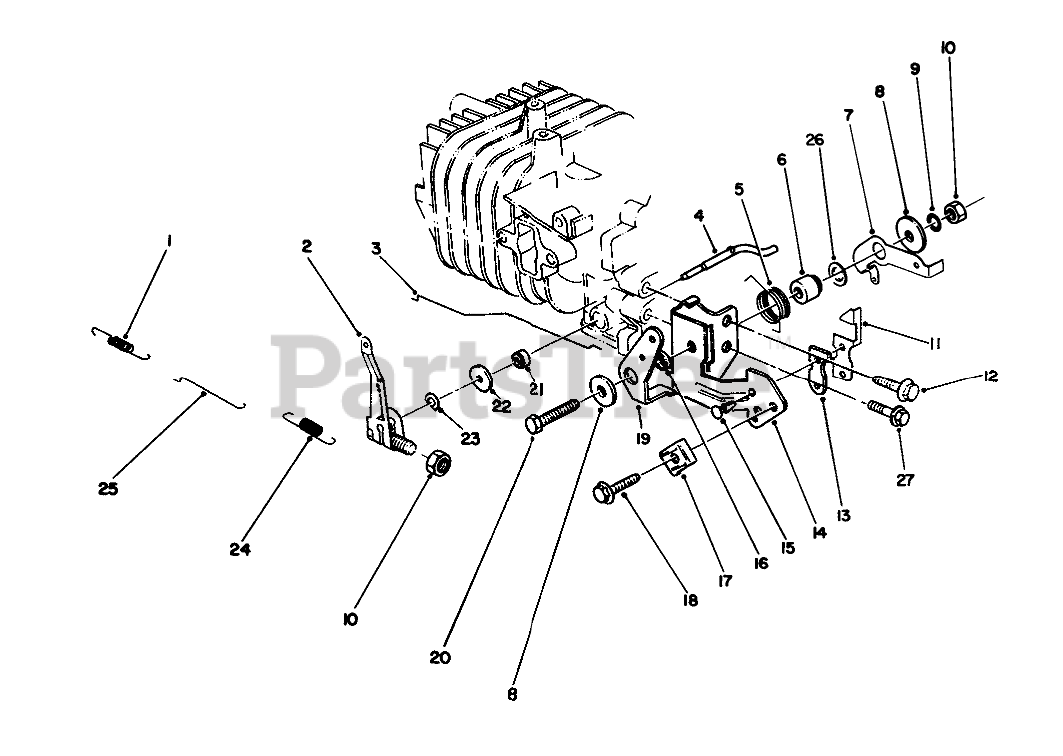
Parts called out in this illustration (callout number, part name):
1	SPRING
2	ARM-GOVERNOR
3	ROD-CHOKE
4	Shaft-Govemor
5	SPRING-CHOKE LEVER
6	Gov Lever Spacer
7	LEVER-SPRING, GOVERNOR
8	WASHER
9	LOCKWASHER
11	TERMINAL-KILL SWITCH
13	INSULATOR-KILL SWITCH
14	BRACKET-THROTTLE, CONTROL
15	KILL SWITCH RIVET
16	SPACER-CHOKE LEVER
17	CLAMP
19	LEVER-CONTROL, CHOKE
21	SEAL-OIL
22	WASHER
23	E-RING
24	SPRING-GOVERNOR
25	ROD-CARBURETOR
26	Washer-Gov. Spring Lever
